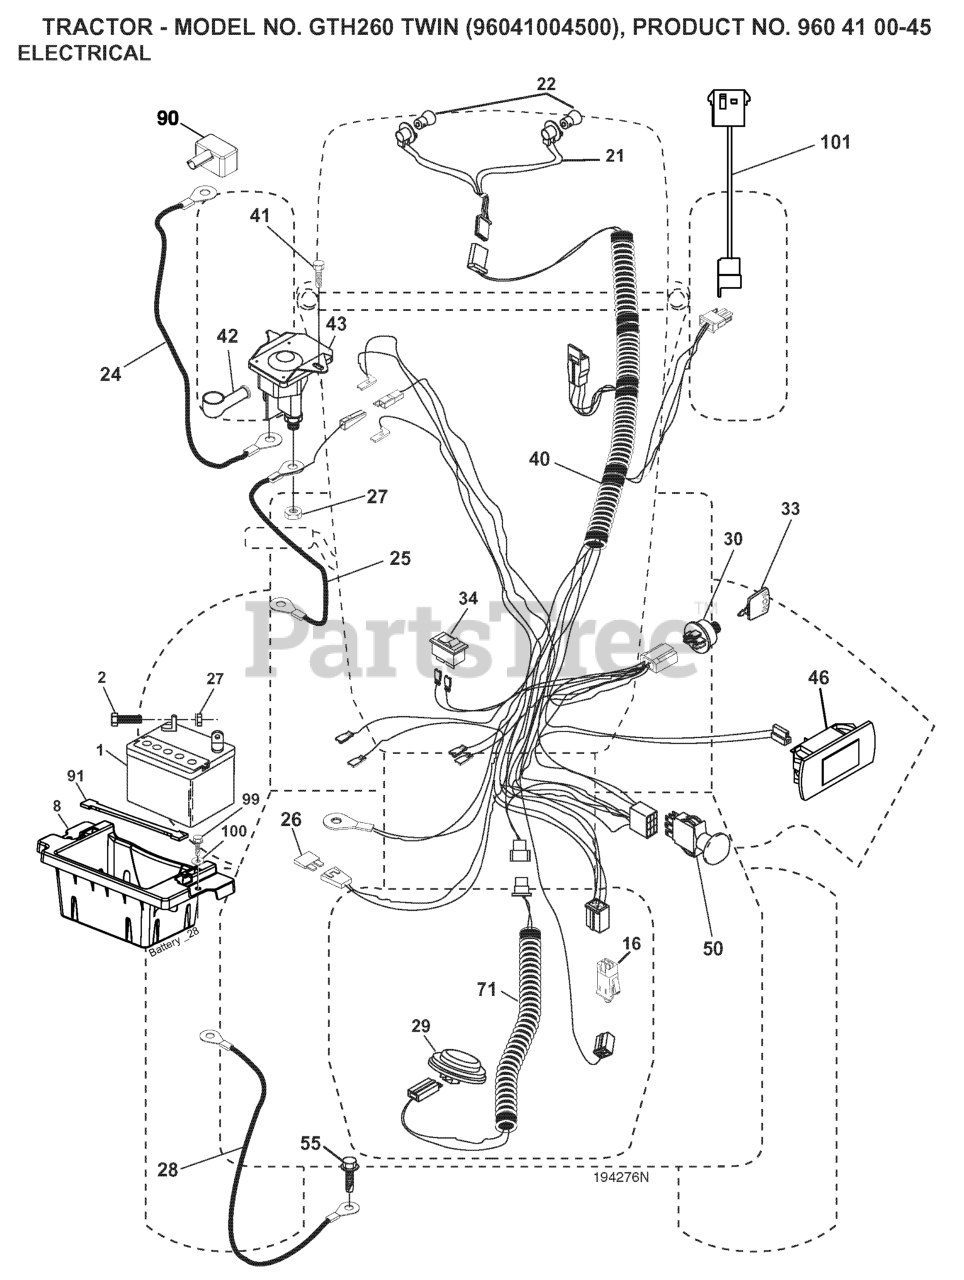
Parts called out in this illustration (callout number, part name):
1	BATTERY 12V .35 AMP
2	BOLT.HEX.1/4.X.3/4.DICHROMATE
8	BOX.BATTERY.MOUNT.FRONT.LT
16	SWITCH INTERLOOK PUSH-IN
21	HARNESS ASSY LIGHT
24	CABLE.BATT.POS.WIRE.TG.DA SOL
25	CABLE.START.RED.17.5".
26	FUSE 20AMP
27	NUT
28	CABLE GROUND 6 GA 21" 90T BLK
29	SWITCH.SEAT.DELTA.OPC.
30	SWITCH.IGN.DELTA.W.LGH.ROS
33	KEY MLD GEN DELTA
40	HARNESS.IGN.DASH.HUQ/P
41	SCREW
42	TERMINAL COVER
43	SOLENOID.W/BRASS.PLUNGER
46	RP.GUAGE.SRVCMNDR.HRMTR.
50	RP.PTO.SWITCH.8 TERMINAL.BLACK
55	Screw 5/16-18 x 1/2 Hex, Self Tapping 5/16-18 x 1/2
71	HARNESS-CHASSIS SUB
90	COVER.TERMINAL.BATTERY
91	STRAP.BATTERY.MOUNT.FRONT(2 2)
99	SCREW HEXWSHR 1/4-20X3/4
101	PIGTAIL.MATNLK.NEW.HAR
